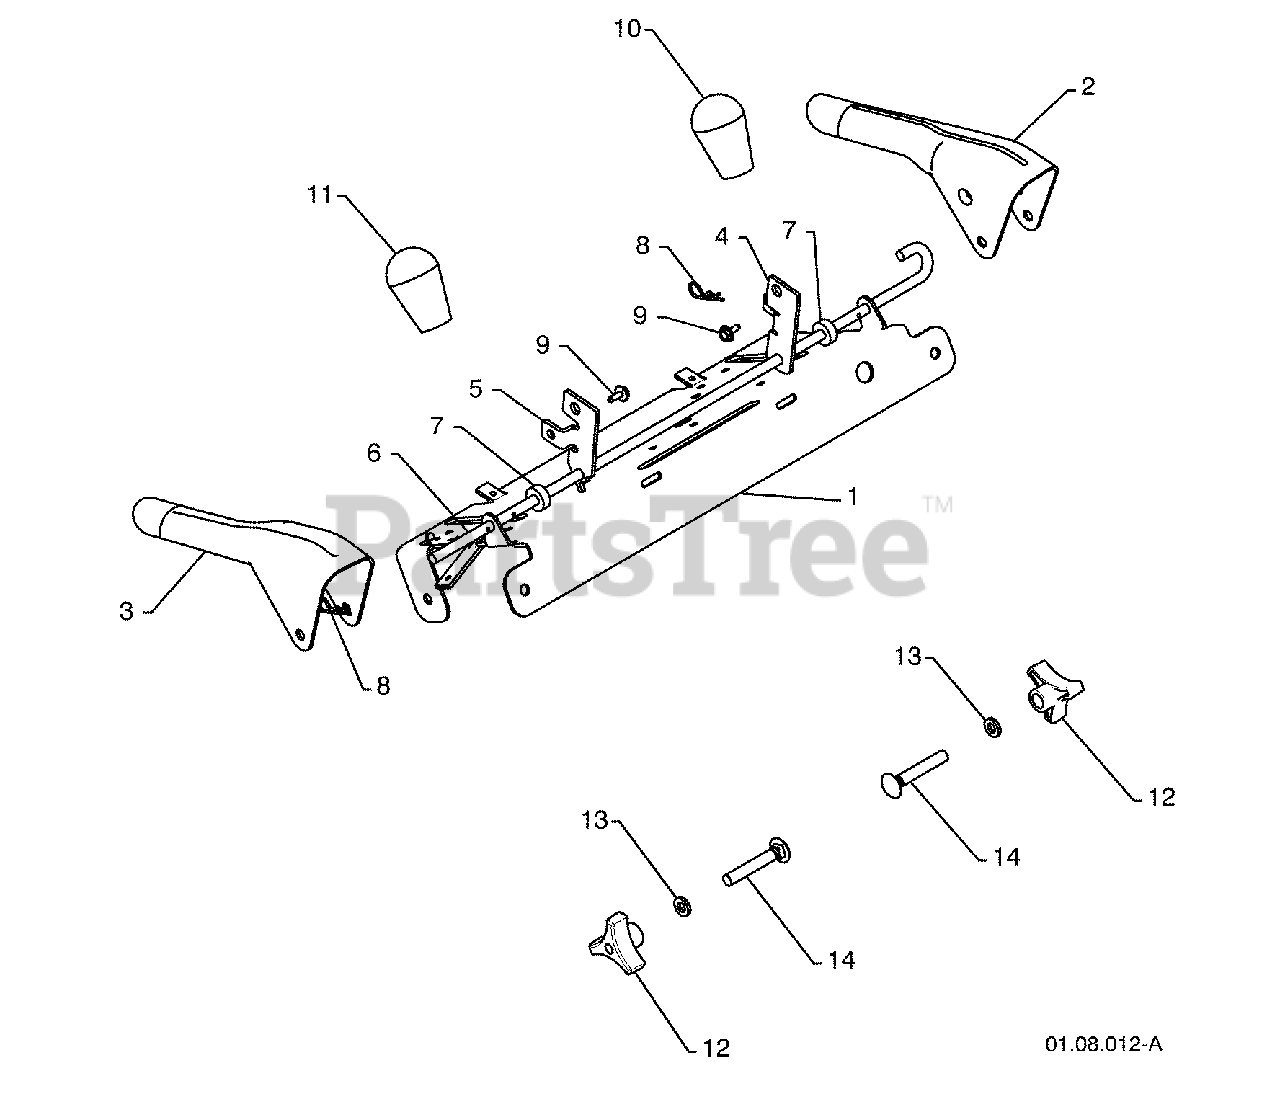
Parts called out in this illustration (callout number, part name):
1	CONTROL PANEL
2	CONTROL LEVER LH
3	CONTROL LEVER RH
4	TRACTION ROD ARM
5	IMPELLER ROD ARM
6	INTERLOCK ROD
9	SCREW 1/4-20 X .50
10	KNOB BLACK
12	HANDLE KNOB
13	WASHER 3/8
14	CARRIAGE BOLT 3/8-16 X 2.25
